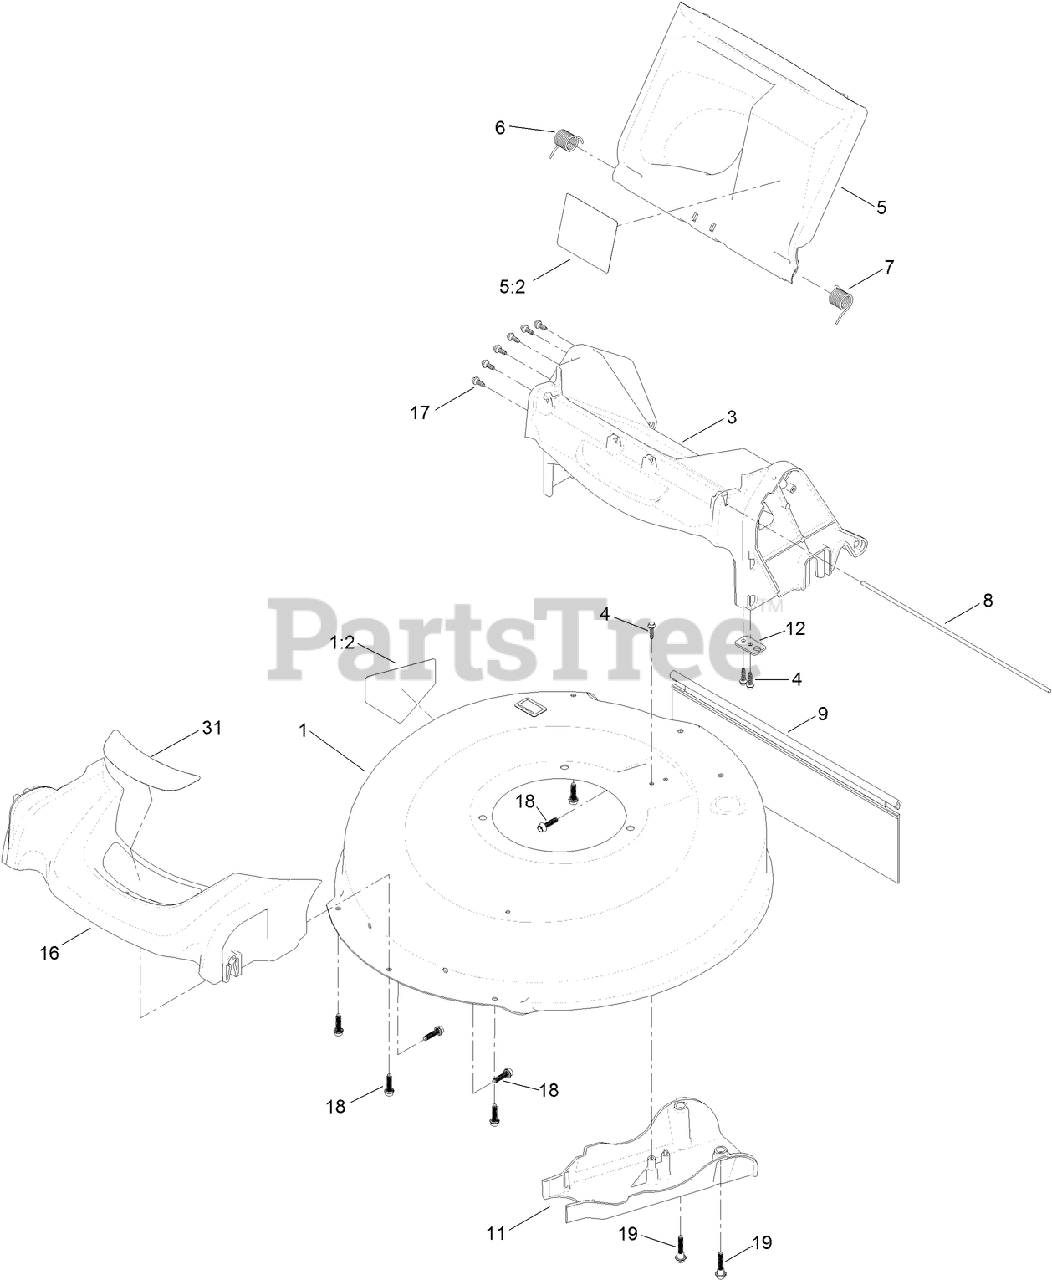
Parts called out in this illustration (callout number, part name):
1	HOUSING ASM
1:2	DECAL-DANGER
4	SCREW-HWH
5	REAR DEFLECTOR ASM
5:2	DECAL-WARNING
6	SPRING-TORSION
7	SPRING-TORSION
9	SHIELD-TRAILING
11	COVER-BELT
12	BRACKET-CABLE
18	SCREW-FLANGE, PLASTIC
19	SCREW-SHOULDER, HHF
31	DECAL-DECK
